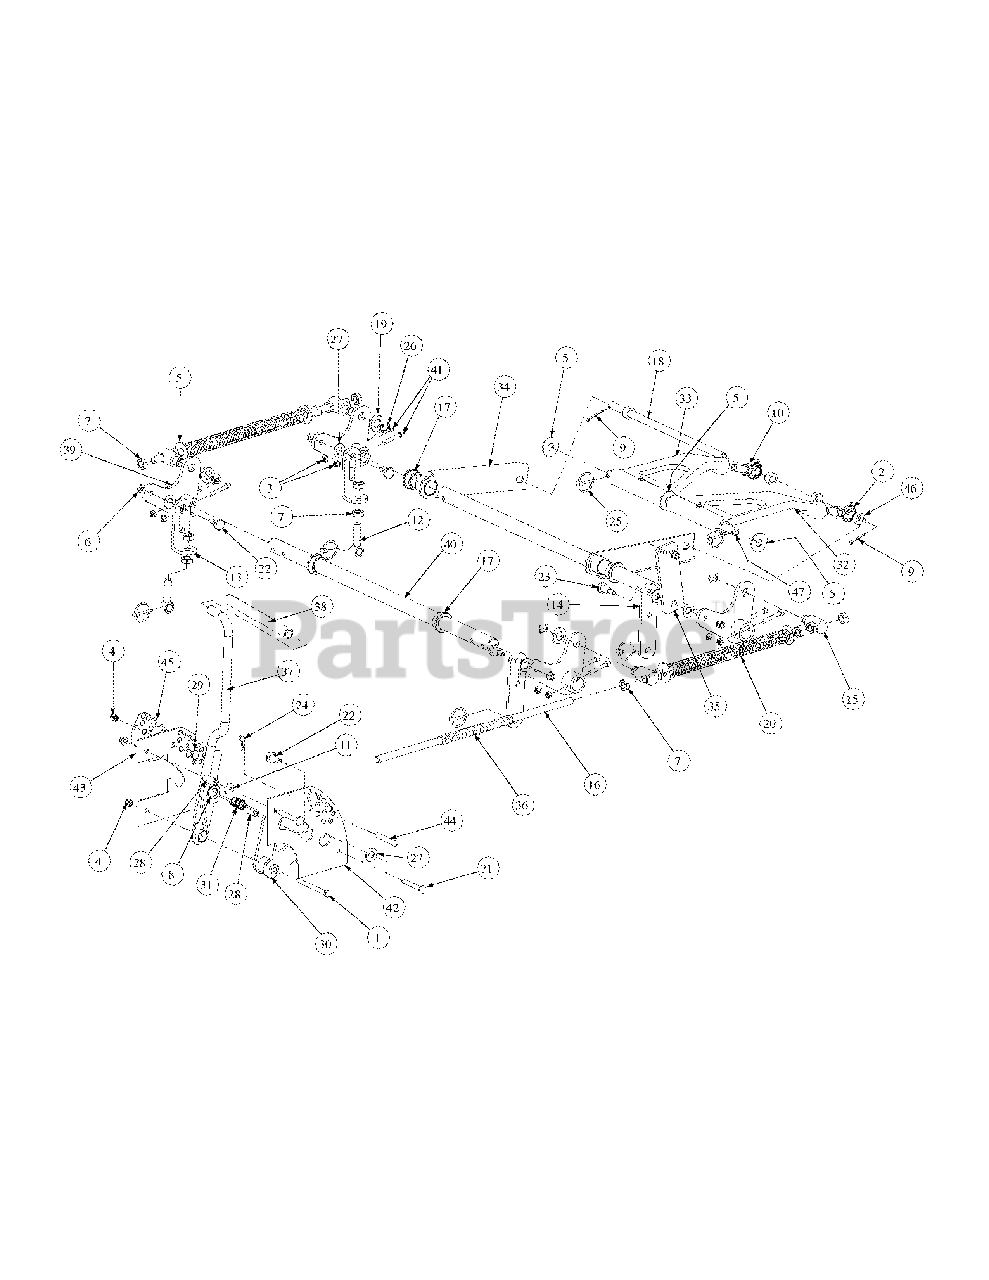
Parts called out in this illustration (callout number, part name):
1	Hex Cap Screw, 3/8-16, 3.75
2	Rod End, Male
3	Nut, 5/16-18, Nylock
4	Nylock Insert Lock Nut, 3/8-16
5	Flat Washer, 5/8
6	Hex Nut, Flange Lock, 3/8-16
7	Jam Nut, 5/8-11
8	Flat Washer, .06, .776, 1.25
9	Cotter Pin, 3/16 x 1-1
10	Jam Nut, 5/8-18
11	Idler Washer
12	Eye Bolt, 5/8ID
13	Eye Bolt Mount Link, 5/8 ID
14	Deck Link
15	Ferule Lift
16	Lift Connector Rod
17	Hex Flange Bearing, 1.25 ID
18	Front Lift Link, Rod Mount
19	Spacer, .812 ID x .268 Lg.
20	Lift Compression Spring
21	Carriage Bolt, 3/8-16, 2.75
22	Shoulder Screw, 0.625 OD x .437 Lg.
23	Shoulder Screw, 0.625 OD x .830 Lg.
24	Cotter Pin, .148 x 3.00
25	Linch Pin, 3/16 Dia.
26	E Clip, 3/4 Dia.
27	Nylon Flat Washer, 5/8
28	Spacer, .39 ID x .63 OD x 1.442
29	Shoulder Screw, .50 OD x 0.27
30	Lift Pivot Assembly
31	Lift Handle Spring
32	Bearing Lift Brace Assembly, Right Hand
33	Bearing Lift Brace Assembly, Left Hand
34	Front Frame Strut Assembly
35	Lift Link Adjustment
36	Hose, 5/8 ID 13/16 OD, 8" LG
37	Lift Handle Assembly
38	Lift Handle Grip
39	Bellecrank Weldment Assembly
40	Deck Lift Shaft
41	Socket Head Cap Screw, 5/16-18 x 2
42	Outer Lift Index Plate
43	Inner Lift Index Plate
44	Clevis Pin, .438 Dia. x 2.625 Lg.
45	Decal Height Indicator
46	Spacer, .630 ID x 1.06 OD x .440
47	Lift Link Rod
